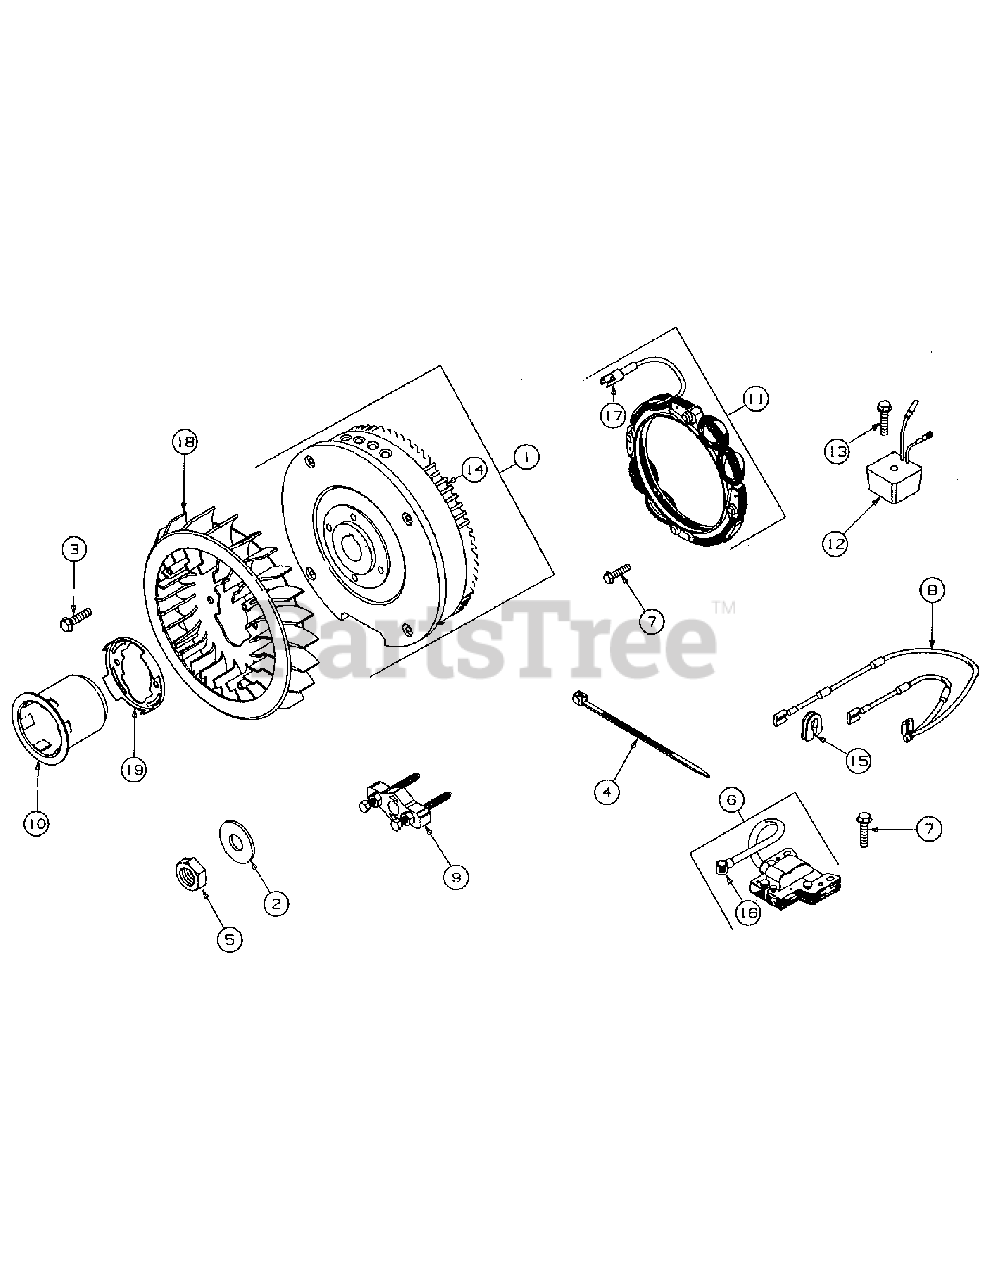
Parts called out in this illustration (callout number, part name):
1	Flywheel, Magneto
2	Washer, Spring
3	Screw, Fan Retainer
4	Tie, Cable
6	Armature, Magneto
7	Screw, Mounting
8	Wire, Ground
9	Puller, Flywheel
10	Hub, Starter
11	Stator, Alternator
12	Regulator, Alternator
13	Screw, Hex Head
14	Gear, Flywheel Ring
15	Grommet
16	Terminal, Ignition Cable
17	Connector Assembly
18	Fan, Flywheel
19	Retainer, Fan
